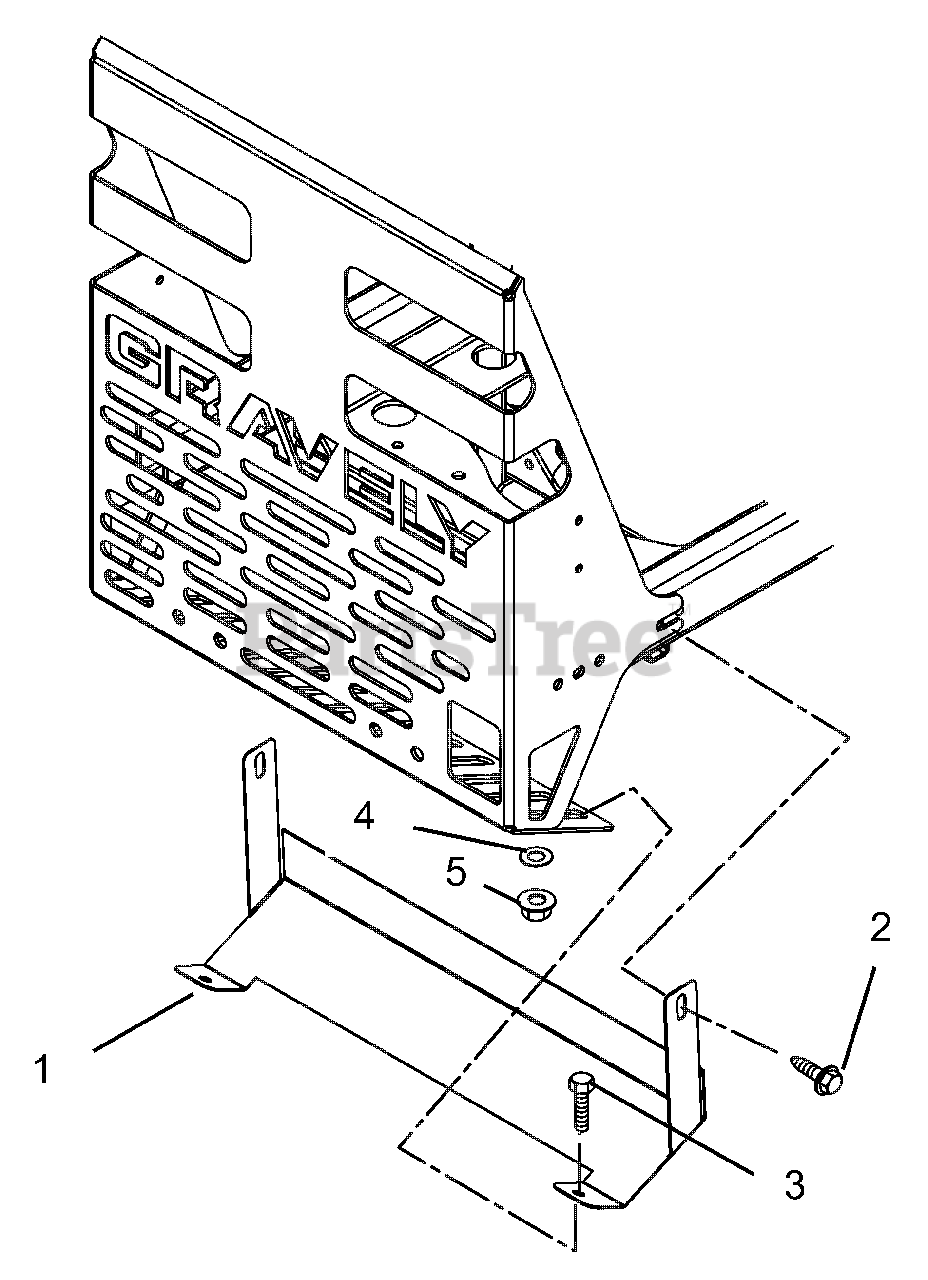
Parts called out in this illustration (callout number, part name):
1	SHIELD - HEAT - IZ
2	@SCR-TAP .38-16X.50 HWH TR YWZ
3	WMT, DECK IDLER PIVOT ARM
4	@WSHR-FL-STL.438X1.00X.083 YWZ
5	@NUT-LK-TOP-FLG .38-16 YWZC
